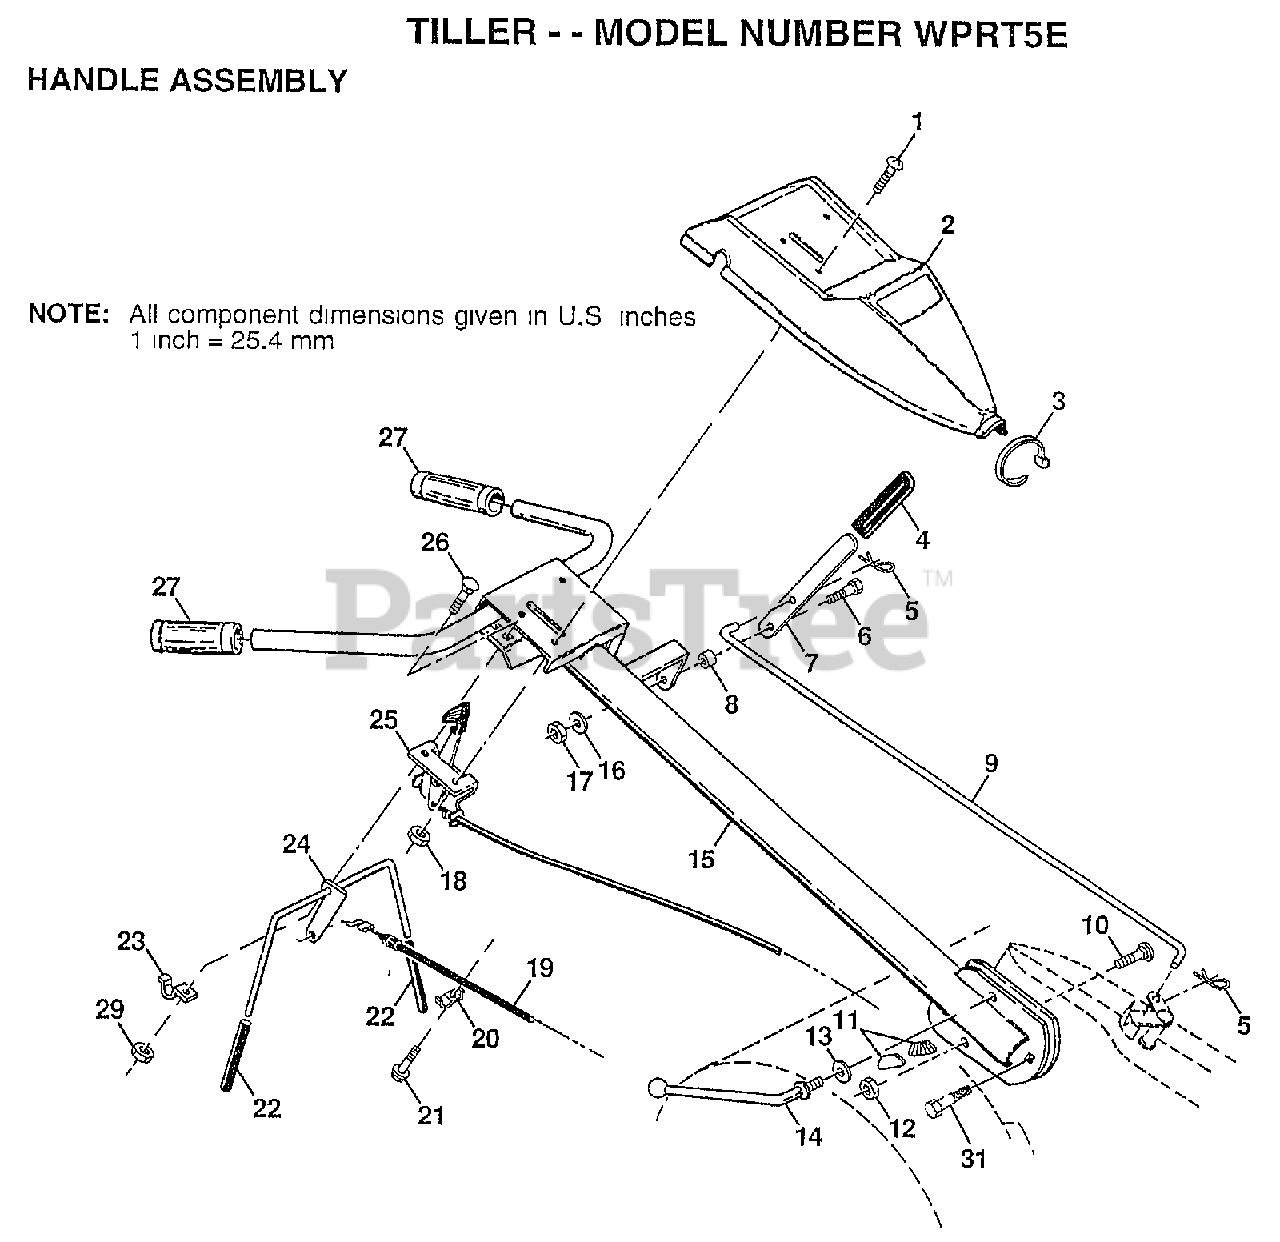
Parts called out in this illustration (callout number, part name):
1	SCREW.PNHD.10-24
2	"PANEL,CONT TI"
3	TIE CABLE CRT
4	GRIP T
5	RETAINER M
6	SHOULDER BOLT ST
7	SHIFT HANDLE CRT
8	GROMMET CRT
9	SHIFT ROD CRT
10	BOLT D
11	LOCK CRT
12	LOCKNUT
13	WASHER CRT
14	LEVER LOCK CRT
16	LOCKWASHER
19	CABLE.CLUTCH.48.Z
20	CONDIUT CLIP T
22	GRIP BAR CRT
24	"ASSY CONTROL, BAR"
25	"CONT,THROTTLE"
26	BOLT
29	NUT
31	BOLT PIVOT
